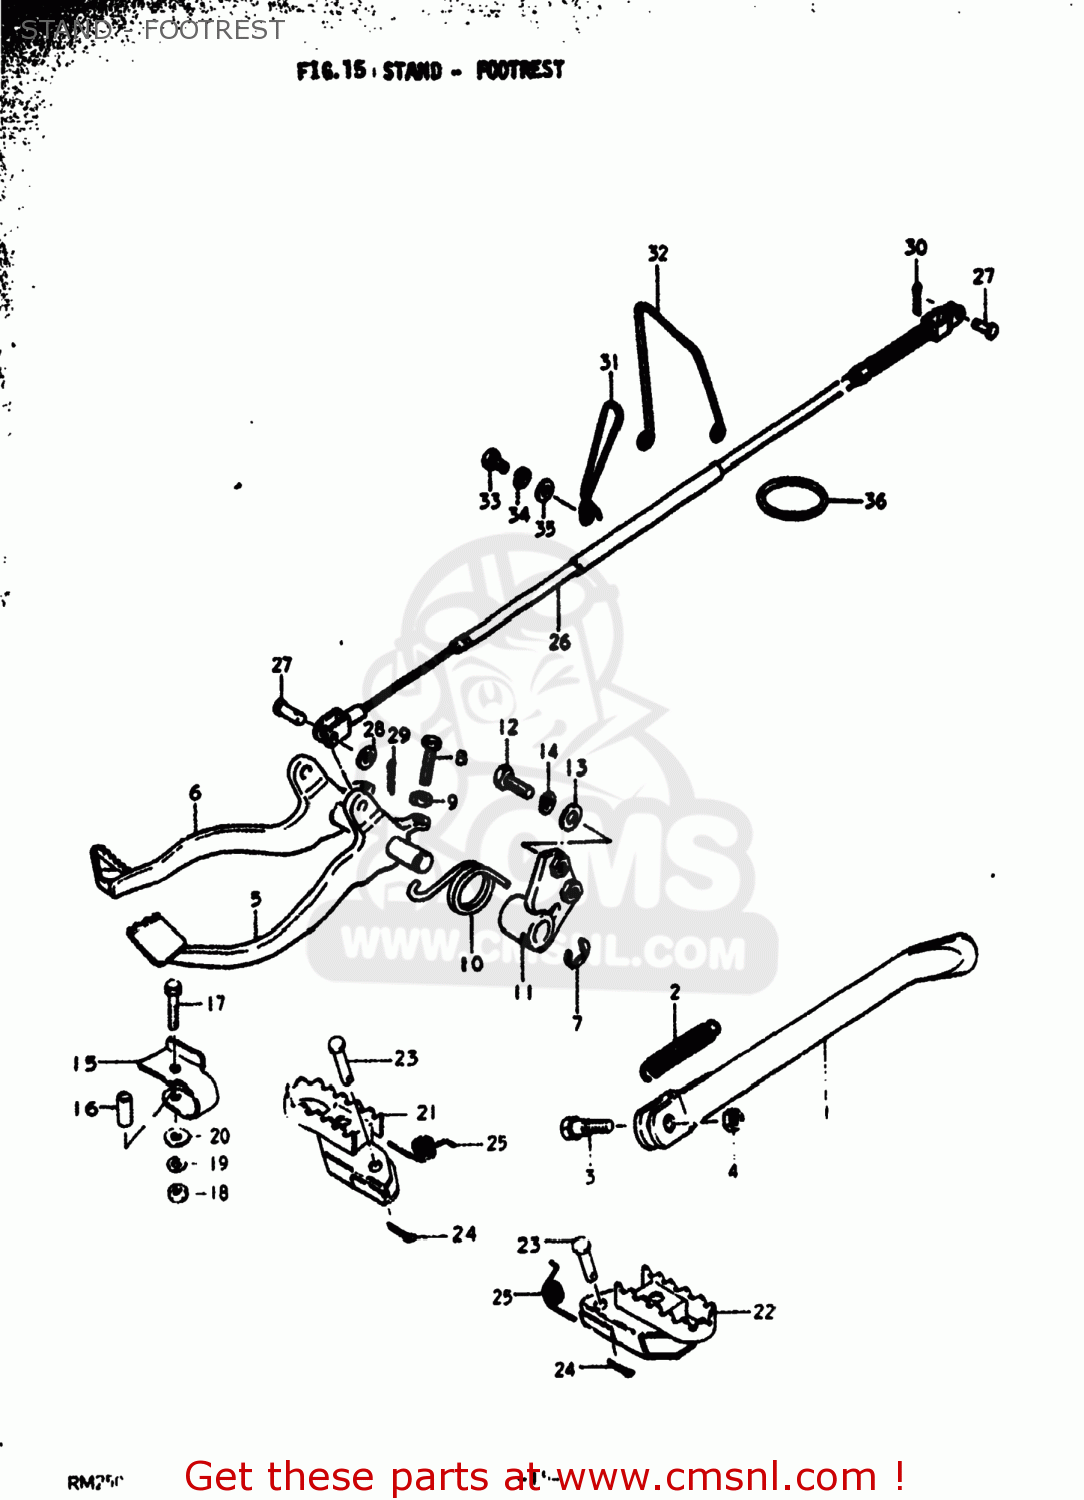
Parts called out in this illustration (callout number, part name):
1	STAND,PROP
2	SPRING
3	BOLT(10X30)
4	NUT
5	PEDAL,BRAKE
6	PEDAL,BRAKE
7	E RING
8	BOLT(6X23)
9	NUT
10	SPRING
11	VALVE ASSEMBLY,WHEEL RIM
12	BOLT,8X1.25X2
13	WASHER
14	LOCK WASHER
15	HANDLE
17	BOLT
18	NUT
19	LOCK WASHER
20	WASHER (6.5X18X2)
21	FOOTREST,FRONT
22	FOOTREST
23	PIN
24	PIN 20X20
25	SPRING
26	CABLE,RR BRAKE
27	PIN(L:17.5)
28	WASHER
29	PIN 20X20
30	PIN
31	GUIDE,CABLE
32	GUIDE,CABLE
33	BOLT
34	LOCK WASHER
35	WASHER
36	O RING,RR BRAKE CABLE
